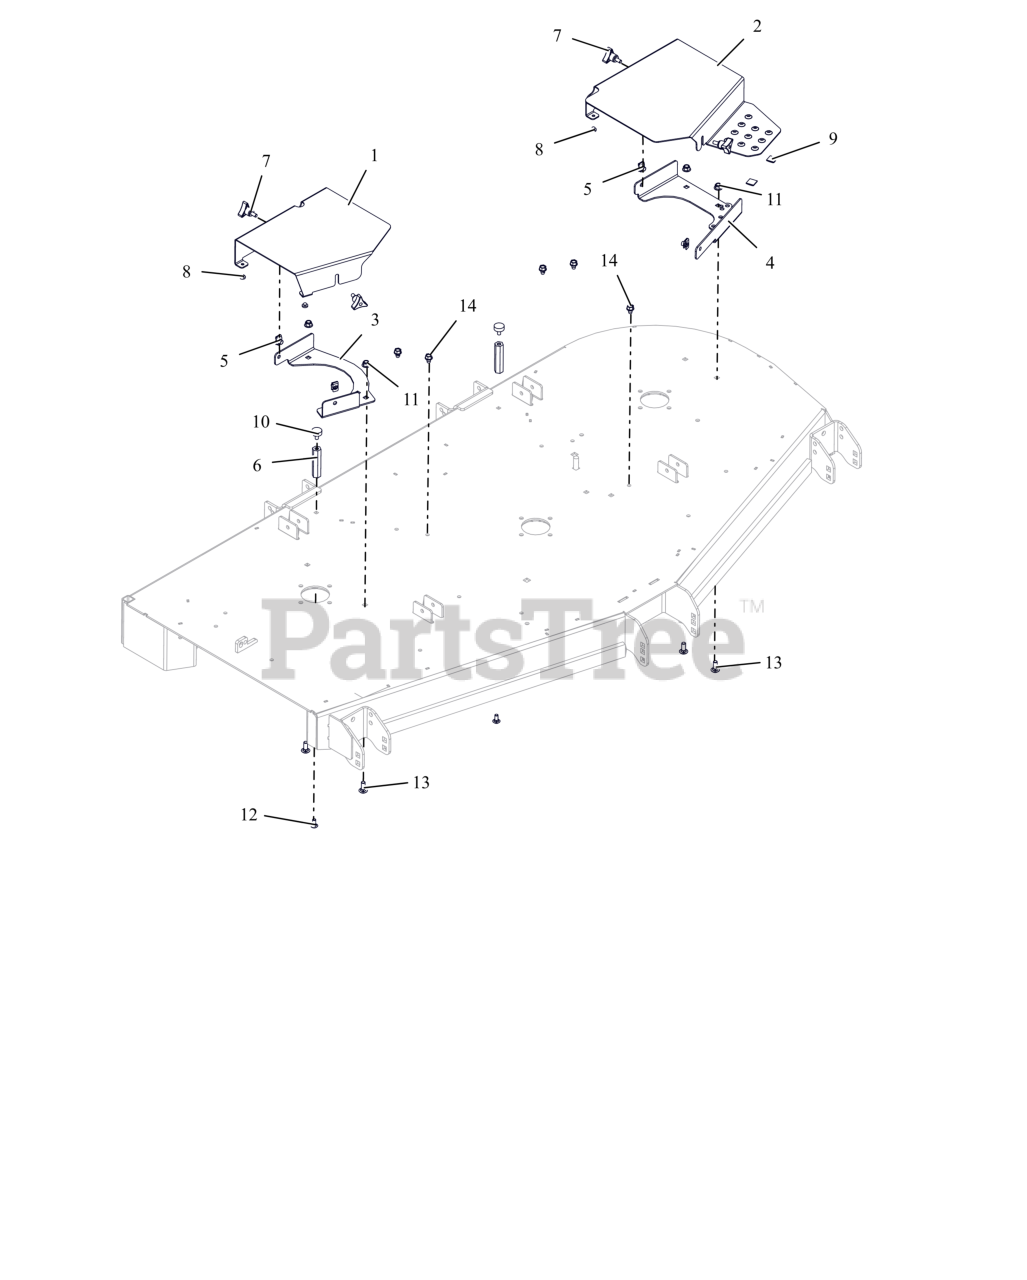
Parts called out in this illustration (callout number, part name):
1	GUARD, RH DECK - RED
2	GUARD, LH BELT - RED
3	BRKT, RH BELT GUARD MTG - RED
4	BRKT, LH BELT GUARD MTG - RED
5	NUT-CLIP RETAINER 5/16-18X.56
6	NUT, COUPLING .312-18 X 3.250
7	KNOB,WING STUD 5/16-18 X .75
8	BUMPER GROMMET
10	BUMPER, RUBBER
11	NUT,NYL-FLG .38-16 GF ZCC
12	BTL,RHSN .313-18 X 0.75 G5 ZCC LT
13	BLT, RHSN .38-16X1.00 G5 ZCC
14	SCR,TAP .375-16X.50 HWH TR ZCC
